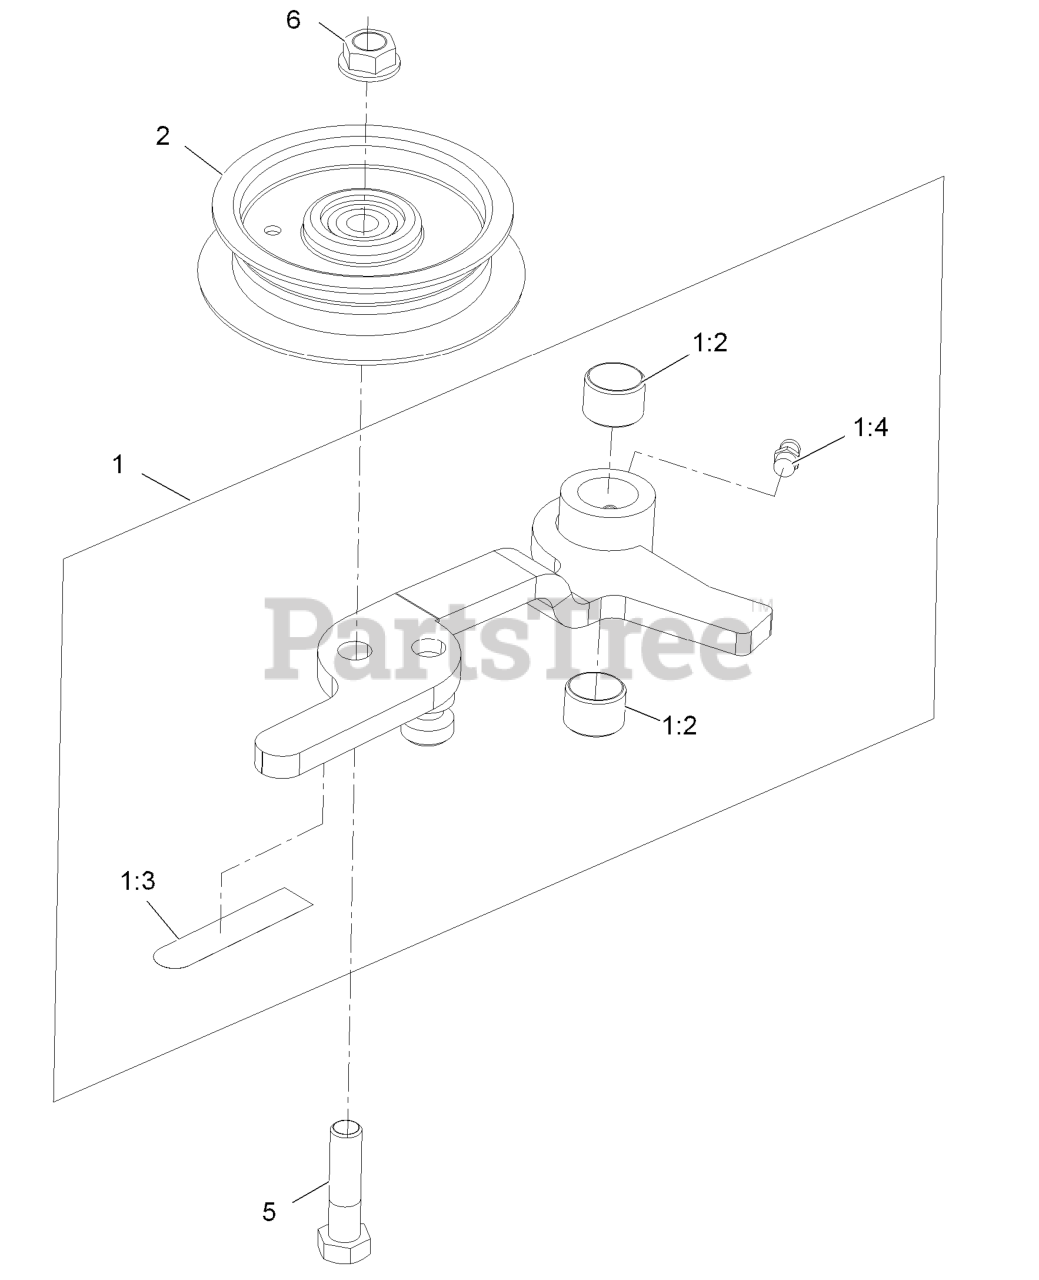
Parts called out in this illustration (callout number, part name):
1	Idler Assy With Bushings, Zerk, And Decal
1:2	Bearing
1:3	Decal-Warning
1:4	Zerk-1/4-28 Str
2	Idler-Flat
5	Screw-HH 3/8-16 X 1 1/2
6	Nut-Whizlock 3/8-16
